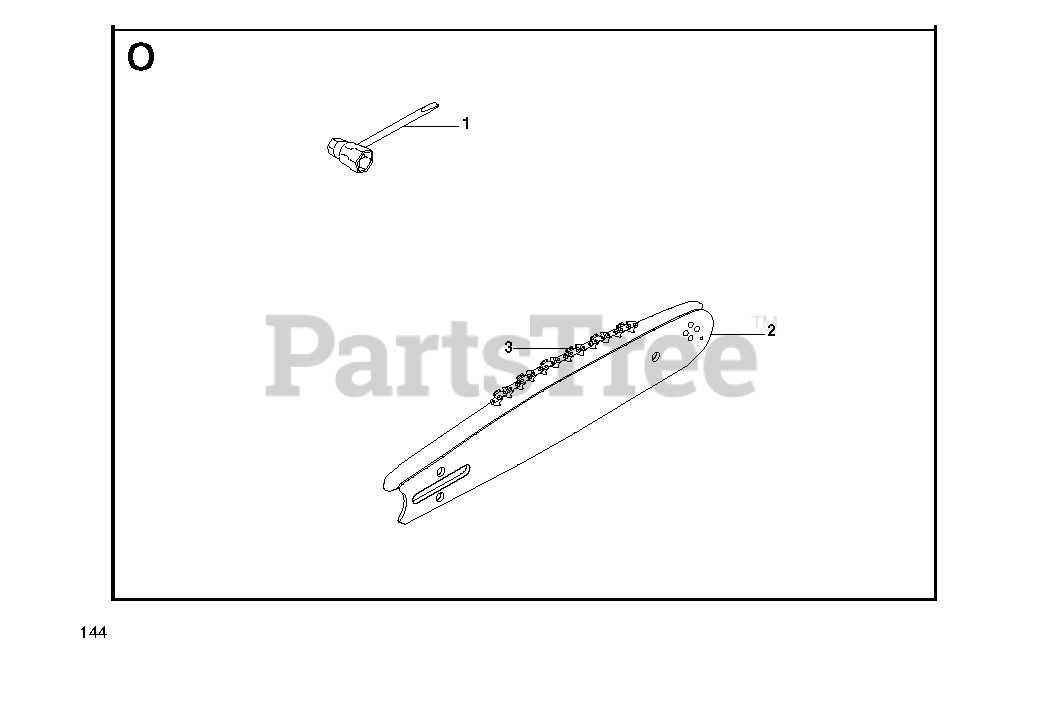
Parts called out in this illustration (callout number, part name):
1	COMBI TOOL
2	G7020 20" bar(533841) GZ7000
2	G7024 24" bar(533842) GZ7000
2	G7028 28" bar(533843) GZ7000
